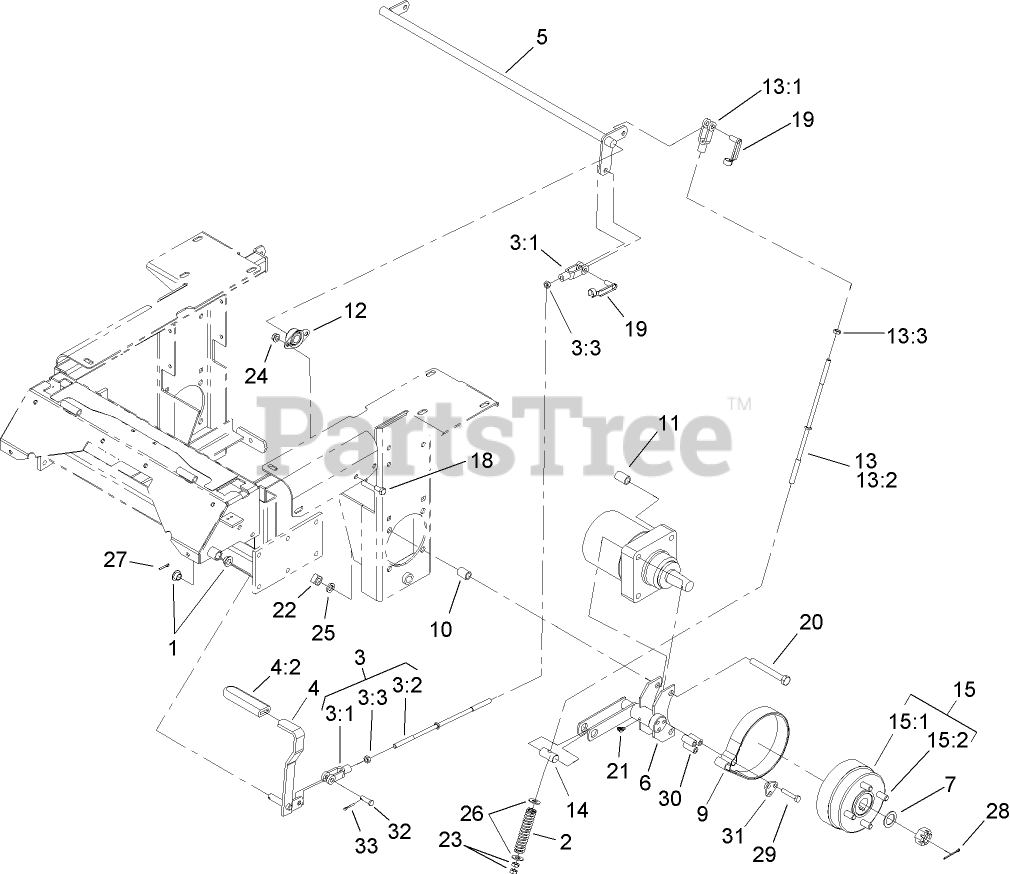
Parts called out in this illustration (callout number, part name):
1	BEARING-CONTROL
2	SPRING-BRAKE
3	Brake Rod And Yoke ASM
3:1	YOKE-LINKAGE, BRAKE
3:2	ROD-BRAKE
3:3	NUT-HEX
4	BRAKE LEVER ASM
4:2	GRIP-LEVER
5	SHAFT-BRAKE
6	BRACKET-BRAKE
7	WASHER-SPACER
9	BAND-BRAKE
10	SPACER-WHEEL, SHORT
11	SPACER-WHEEL, LONG
12	BEARING-FLANGE, SIDE
13	Brake Rod And Yoke ASM
13:1	YOKE-LINKAGE, BRAKE
13:2	ROD-BRAKE
13:3	NUT-HEX
14	PIN-TRUNION
15	WHEEL HUB ASM
15:1	HUB-WHEEL
15:2	STUD-WHEEL
18	SCREW-HH
19	Pin-Spring, Clevis
20	SCREW-HH
21	FITTING-GREASE
22	NUT-SQUARE
23	NUT-HEX
24	NUT-HHF, WHIZ
25	WASHER-LOCK
26	WASHER-FLAT
27	PIN-COTTER
28	PIN-COTTER
29	SCREW-HH
30	SPACER
31	RETAINER-BAND, BRAKE
32	PIN-CLEVIS
33	PIN-COTTER
